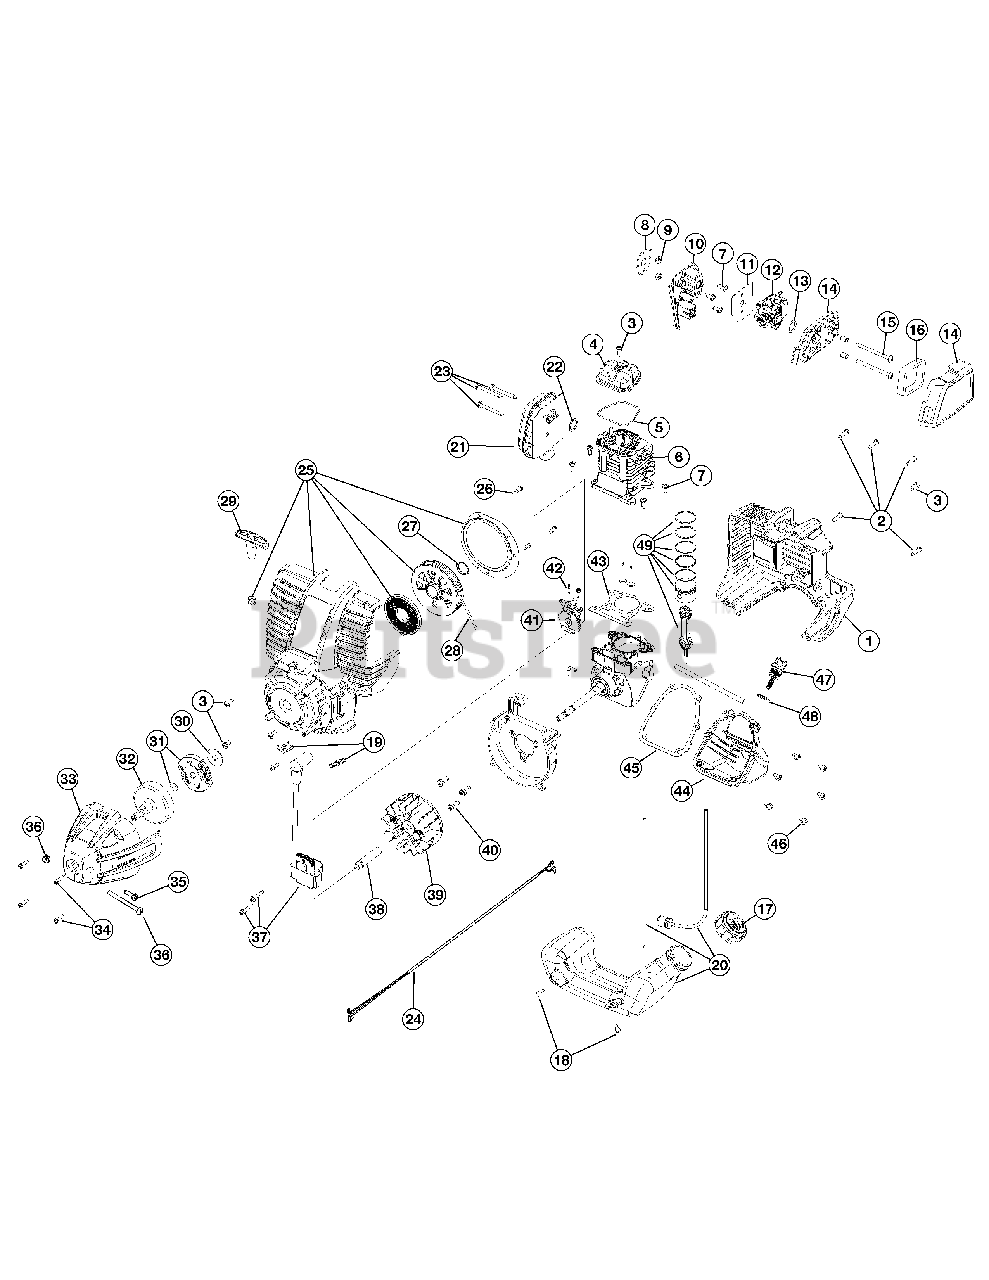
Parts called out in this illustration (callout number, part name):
1	Engine Cover
3	Screw
4	Valve Cover
5	Valve Cover Gasket
6	Cylinder Assembly (includes 5, 7 & 43)
7	Cylinder Screw
8	Insulator Gasket
9	Nut
10	Insulator (includes 11)
11	Carburetor Gasket
12	Carburetor w/Primer
13	Carburetor O-Ring
14	Air Filter Cover Assembly
15	Air Filter Mounting Screw
16	Air Filter
20	Fuel Tank Assembly (includes 17)
21	Muffler Assembly (includes 22 & 23)
22	Muffler Gasket
23	Muffler Mounting Screw
25	Starter Housing Assembly (includes 3 & 26-29)
26	Plate Screw
27	Push Nut
29	Pull Handle
30	Washer
31	Clutch Assembly
32	Clutch Drum
33	Clutch Cover Assembly (includes 34-36)
34	Cover Screw
35	Anti-Rotation Screw
36	Clamping Screw Assembly
37	Ignition Module Assembly
38	Spacer
40	Shroud Screw
41	Cam Bracket Assembly
42	Cam Bracket Screw
43	Cylinder Gasket
44	Oil Pan (includes 45 & 46)
45	Oil Pan Gasket
46	Oil Pan Screw
47	Dipstick Assembly (includes 48)
49	Piston & Rings
49	Piston, Rod & Rings Assembly
